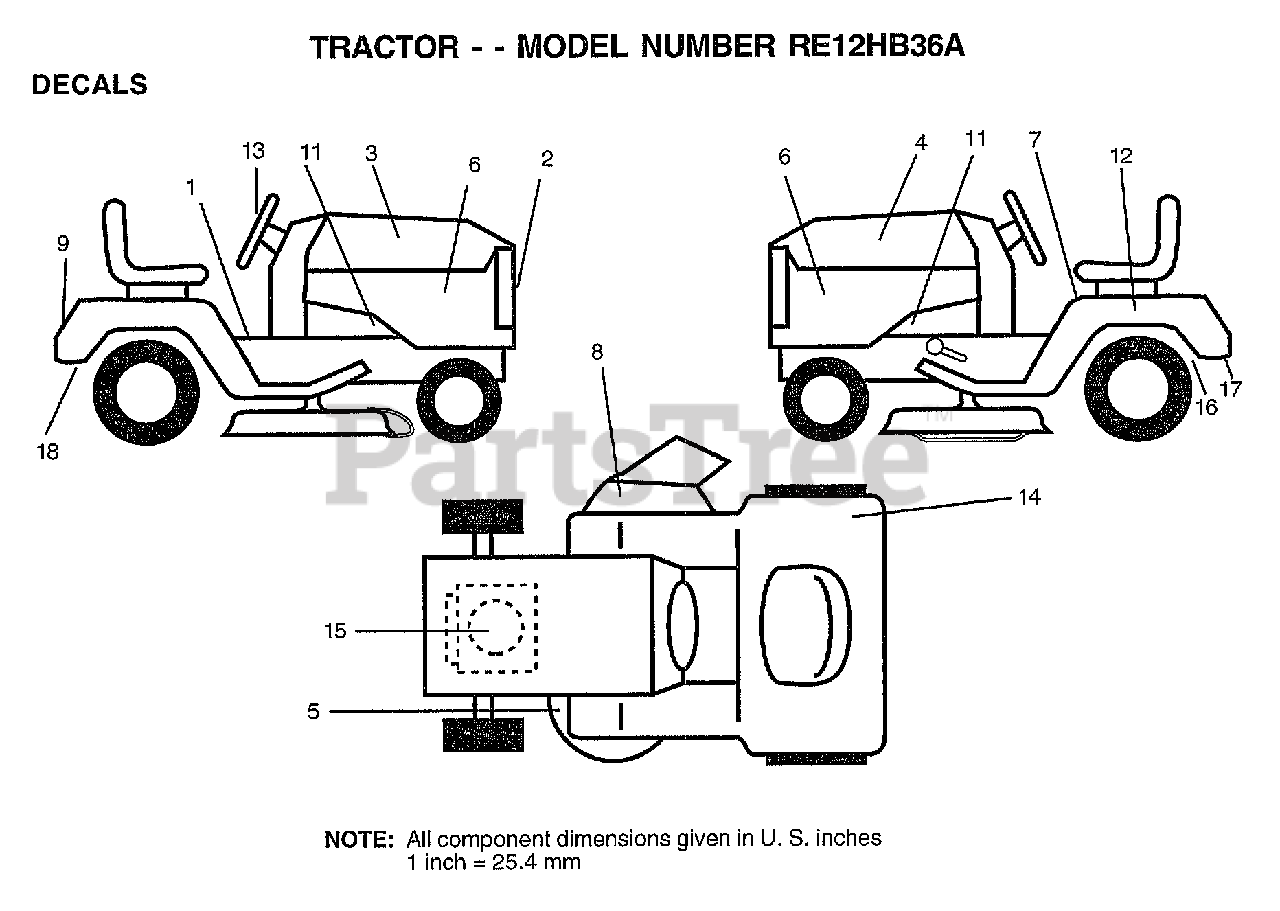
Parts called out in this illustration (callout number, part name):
1	DECAL CLUTCH/BRAK
2	GRILL DECAL
3	DECAL HD RLY RH
4	DECAL HD RLY LH
5	DECAL.V.BELT
6	DECAL
7	DECAL.READ.O.MANU
8	DECAL.DANGER.CUTF
9	FENDER DECAL
11	"DECAL CHASSIS,HOT"
12	DECAL.BATRY.3-3908
13	"DECAL,STR WHL"
15	DECAL, ENGINE
16	DECAL.DRAWBAR.LDL
17	DECAL.DRAWBAR.CTL
18	DECAL.EURO.ST.CE.
